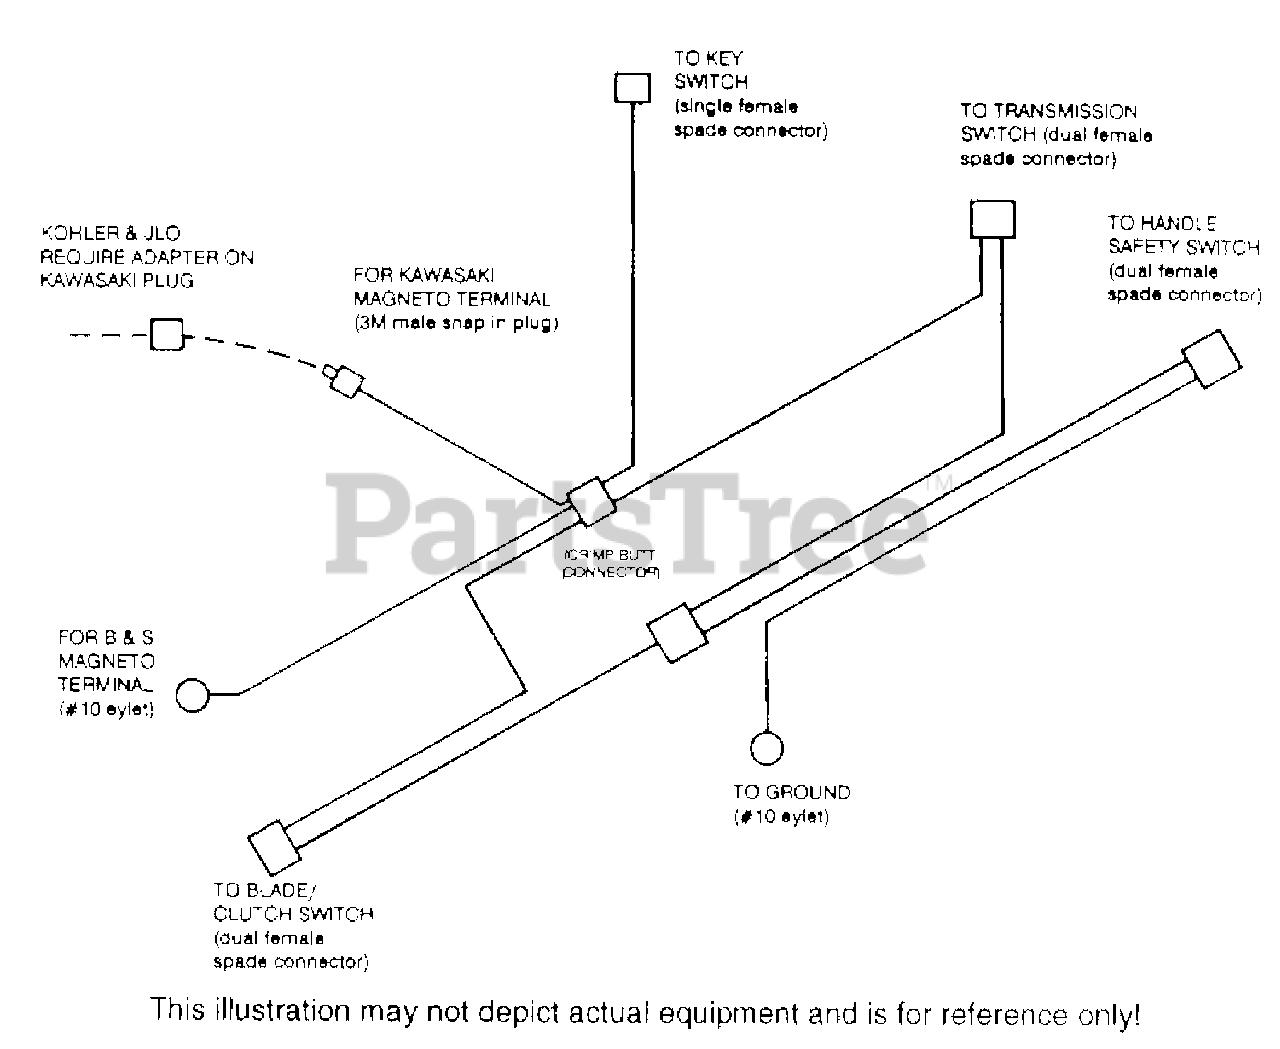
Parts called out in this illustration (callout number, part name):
1B	ENGINE 18HP KOHLER(MV18 PS-58511)
1B	ENGINE 20HP KOHLER EL. ST.(MV20 PS-57508)
2	CABLE CLAMP
6	WIRE HARNESS ELECTRIC START
28	PULLEY, TRACTION DRIVE
31	PULLEY, BLADE DR.(INCL. 31-33)
32	TAPER HUB(FOR 48378)
48	SHORT SQ. NECK CRG. BOLT, 3/8-18 X 1 1/2
49	BATTERY BOX
50	BRACKET, IDLER PULLEY
51	SPACER
52	WASHER, 13/32 X 1-1/2 X 7 GA.
53	BATTERY CLAMP
54	BATTERY COVER
55	BATTERY COVER PAD
61	KEY SWITCH
64	CLAMP, FUEL HOSE
65	PIPE CAP
65	FUEL HOSE(KH ONLY) 1/4 ID X 14 1/8
66	PIPE 4" NIPPLE
68	WING NUT, 1/4-20 ELASTIC STOP
69	BATTERY
80	THROTTLE CONTROL
96	CHOKE CONTROL
99	ROD, CONTROL PIVOT 20"
105	SOLENOID
